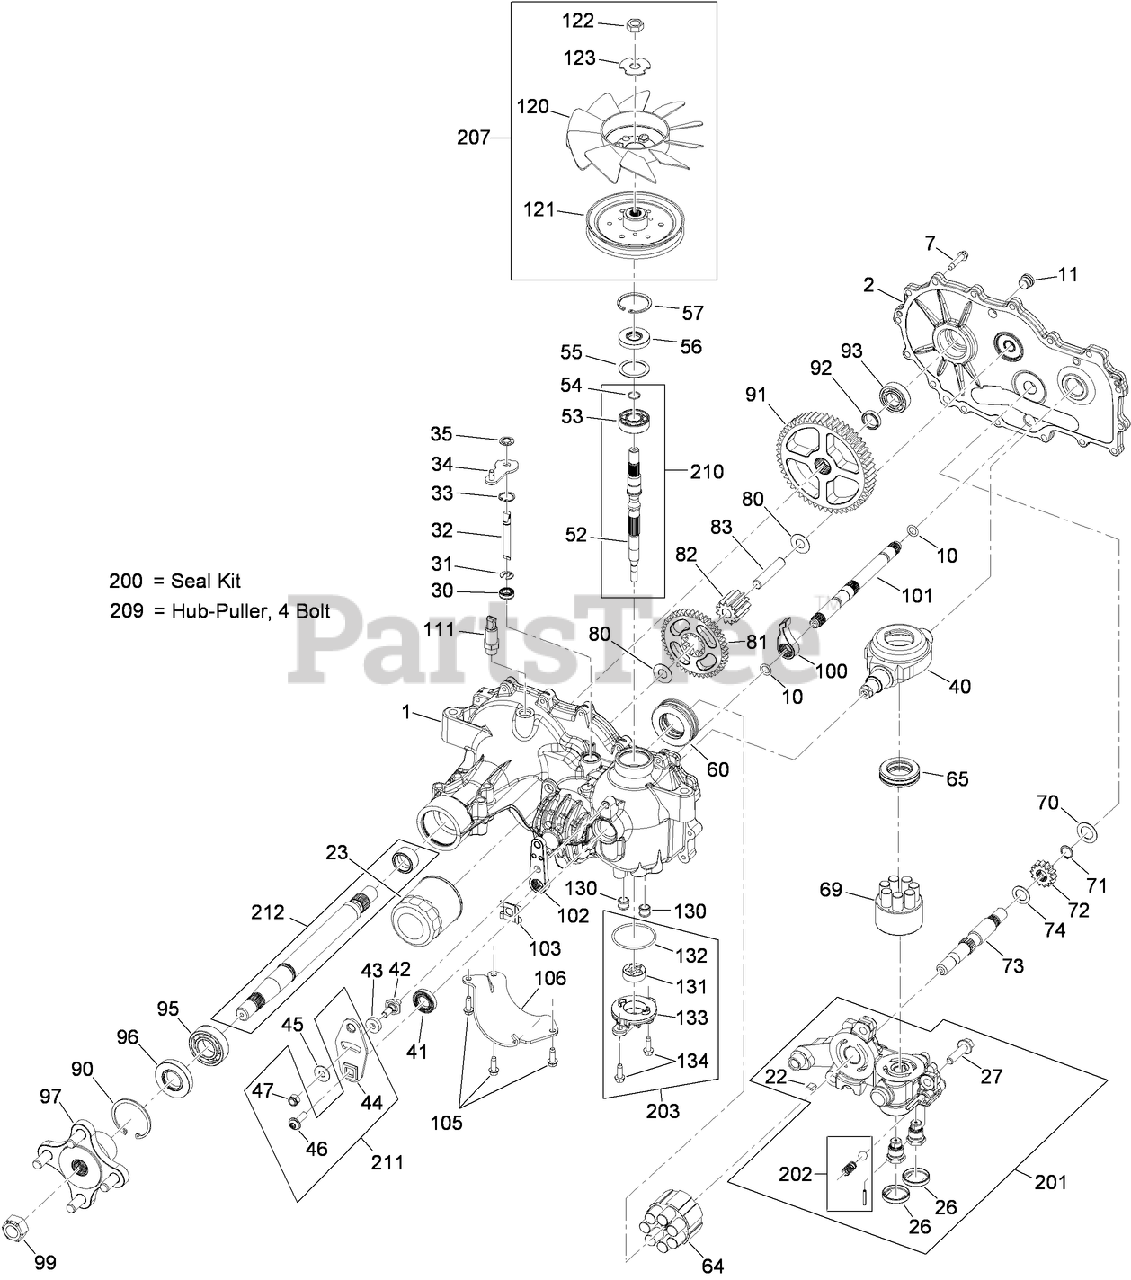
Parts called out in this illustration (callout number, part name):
1	RH MAIN HOUSING KIT
2	RH HOUSING SIDE KIT
7	SCREW-HHF
10	O-RING
11	PLUG-THREAD, STRAIGHT
22	PLATE-BYPASS
23	ELEMENT-OIL FILTER, HYD
26	SEAL-PLUG
27	SCREW-HFHC
30	SEAL-LIP
31	RING-RETAINING, EXTERNAL
32	ROD-BYPASS
33	RING-RETAINING, INTERNAL
34	ARM-BYPASS
35	RING-RETAINING, EXTERNAL
40	SWASHPLATE-TRUNNION
41	SEAL-LIP
43	PUCK-FRICTION
44	ARM-CONTROL
45	WASHER
52	SHAFT-INPUT
53	BEARING-BALL
54	RING-RETAINING
55	SPACER
56	SEAL-LIP
57	RING-RETAINING
60	BEARING-THRUST
64	MOTOR CYLINDER BLOCK KIT
65	BEARING-THRUST
69	PUMP BLOCK ASM
70	WASHER-FLAT
71	RING-RETAINING
72	GEAR-14T
73	SHAFT-MOTOR
74	WASHER
80	WASHER
81	GEAR-45T
82	GEAR-11T
83	PIN-JACKSHAFT
90	RING-RETAINING
91	GEAR-54T
93	BEARING-BALL
95	BEARING-BALL
97	HUB KIT
100	PAWL-BRAKE
102	HANDLE-BRAKE
103	CLIP-RETAINING
111	ADAPTER-STRAIGHT
122	NUT-HEX
123	WASHER-SLOTTED
130	TUBE-CONNECTING
131	GEROTOR ASM
132	O RING-SEAL
133	COVER-CHARGE PUMP
200	SEAL KIT
201	RH CENTER SECTION KIT
202	CHARGE RELIEF KIT
203	CHARGE KIT
210	INPUT SHAFT KIT
211	CONTROL ARM KIT
212	AXLE SHAFT KIT
